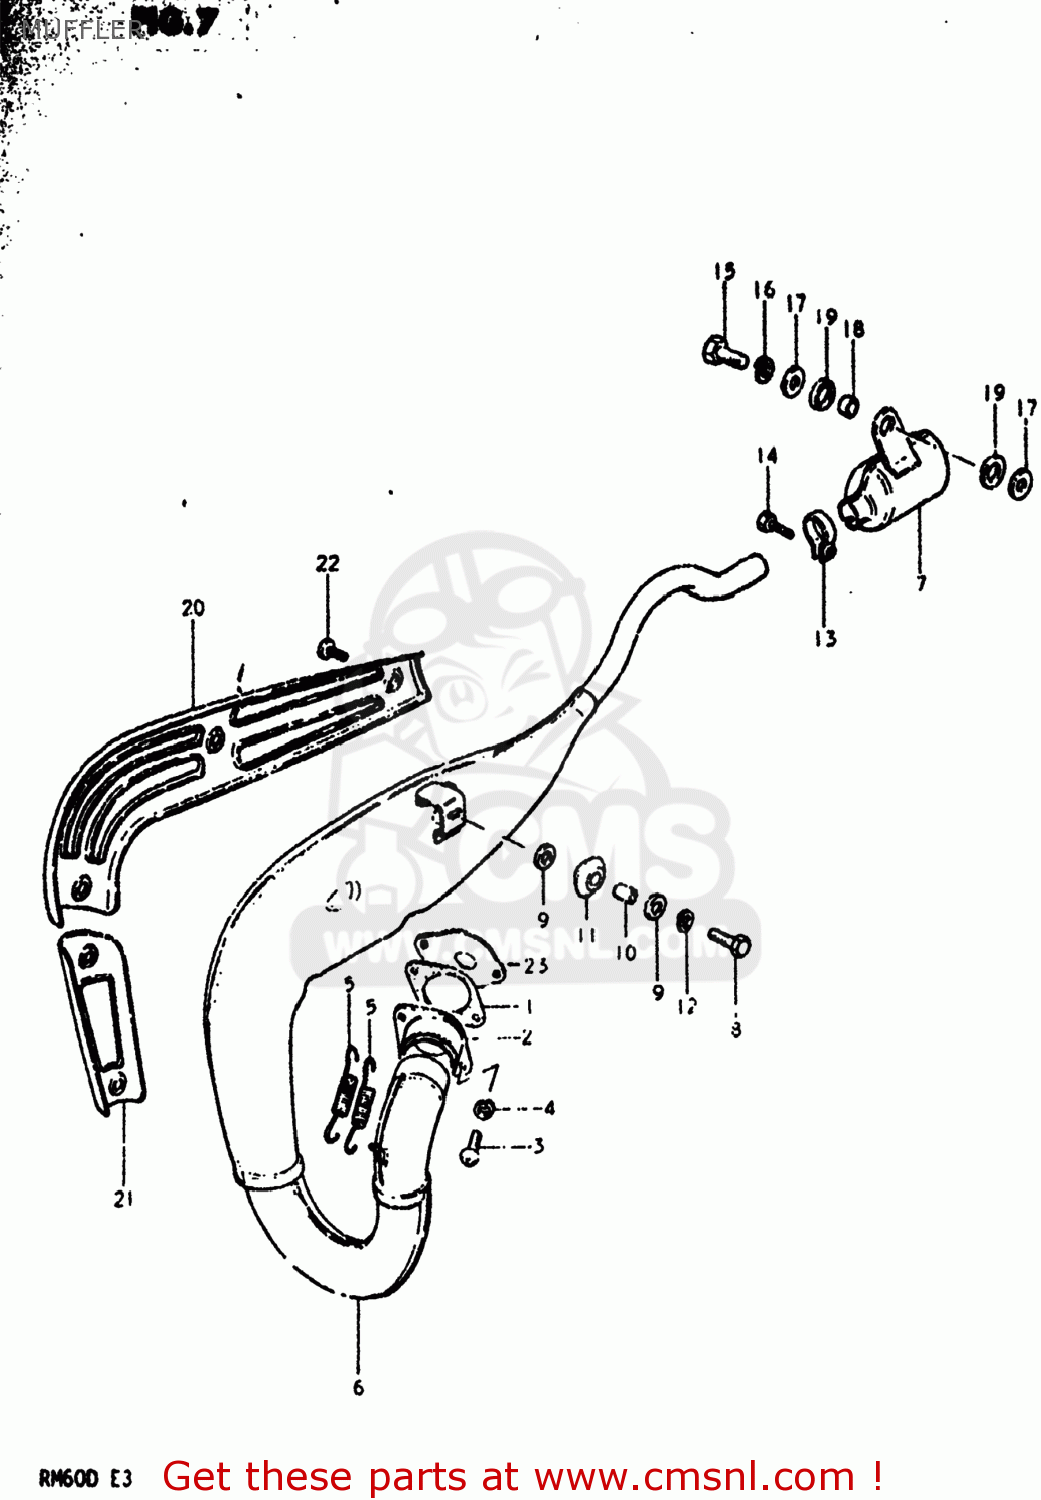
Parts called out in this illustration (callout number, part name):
1	GASKET,EXHAUST PIPE (MCA)
2	PIPE,CENTER EXHAUST
3	SCREW
4	LOCK WASHER
5	SPRING
6	BODY,MUFFLER
7	BODY,MUFFLER
8	BOLT (8X30)
9	WASHER (8.7X22X2)
10	SPACER (8X12X15)
11	DAMPER,MUFFLER,FR
12	LOCK WASHER
13	CLAMP
14	BOLT(6X20)
15	BOLT
16	LOCK WASHER
17	WASHER
18	SPACER (8.6X13.8X9)
19	CUSHION
20	COVER,MUFFLER NO.1
21	COVER,MUFFLER
22	SCREW
23	PLATE,EXHAUST PIPE
